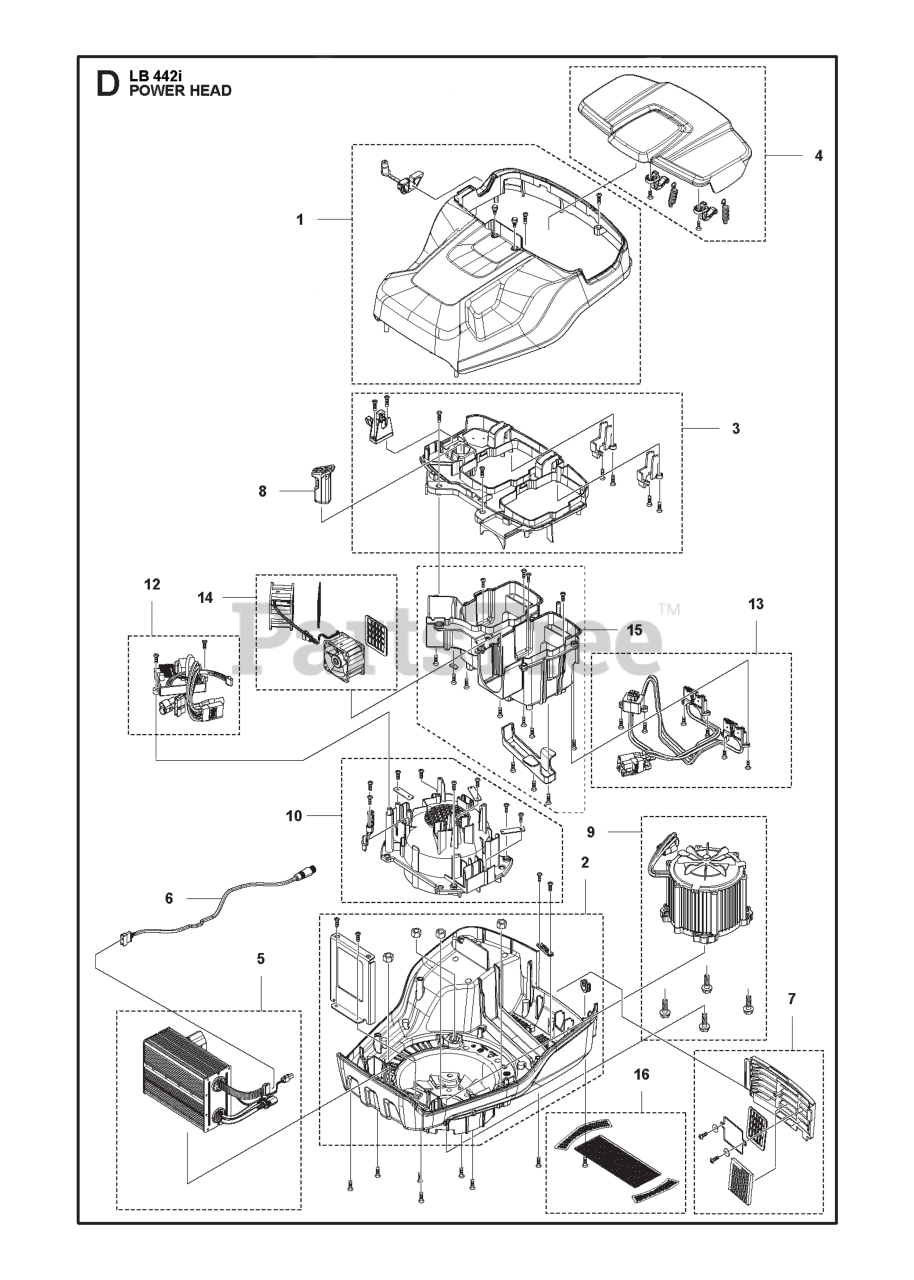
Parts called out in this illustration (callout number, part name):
3	Battery Box
13	Battery Box
14	Battery Box
15	Battery Box
